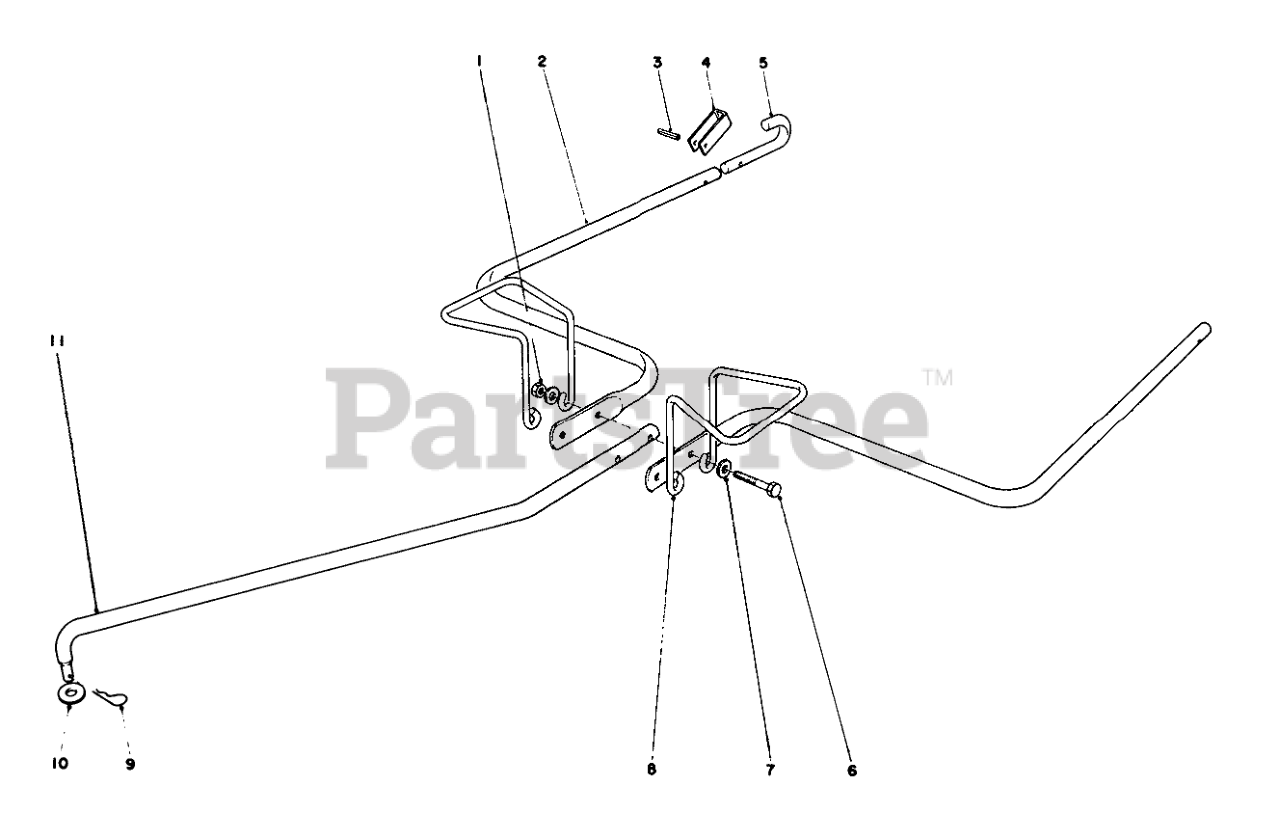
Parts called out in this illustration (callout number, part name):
1	NUT-LOCK, CONE
2	HITCH ARM
3	PIN-ROLL, SLOT
4	HITCH LOCK
5	HOOK HITCH ARM
6	SCREW-HH
7	WASHER-FLAT
8	Support Bag
9	PIN-COTTER
10	PUSH NUT
11	POLE HITCH
